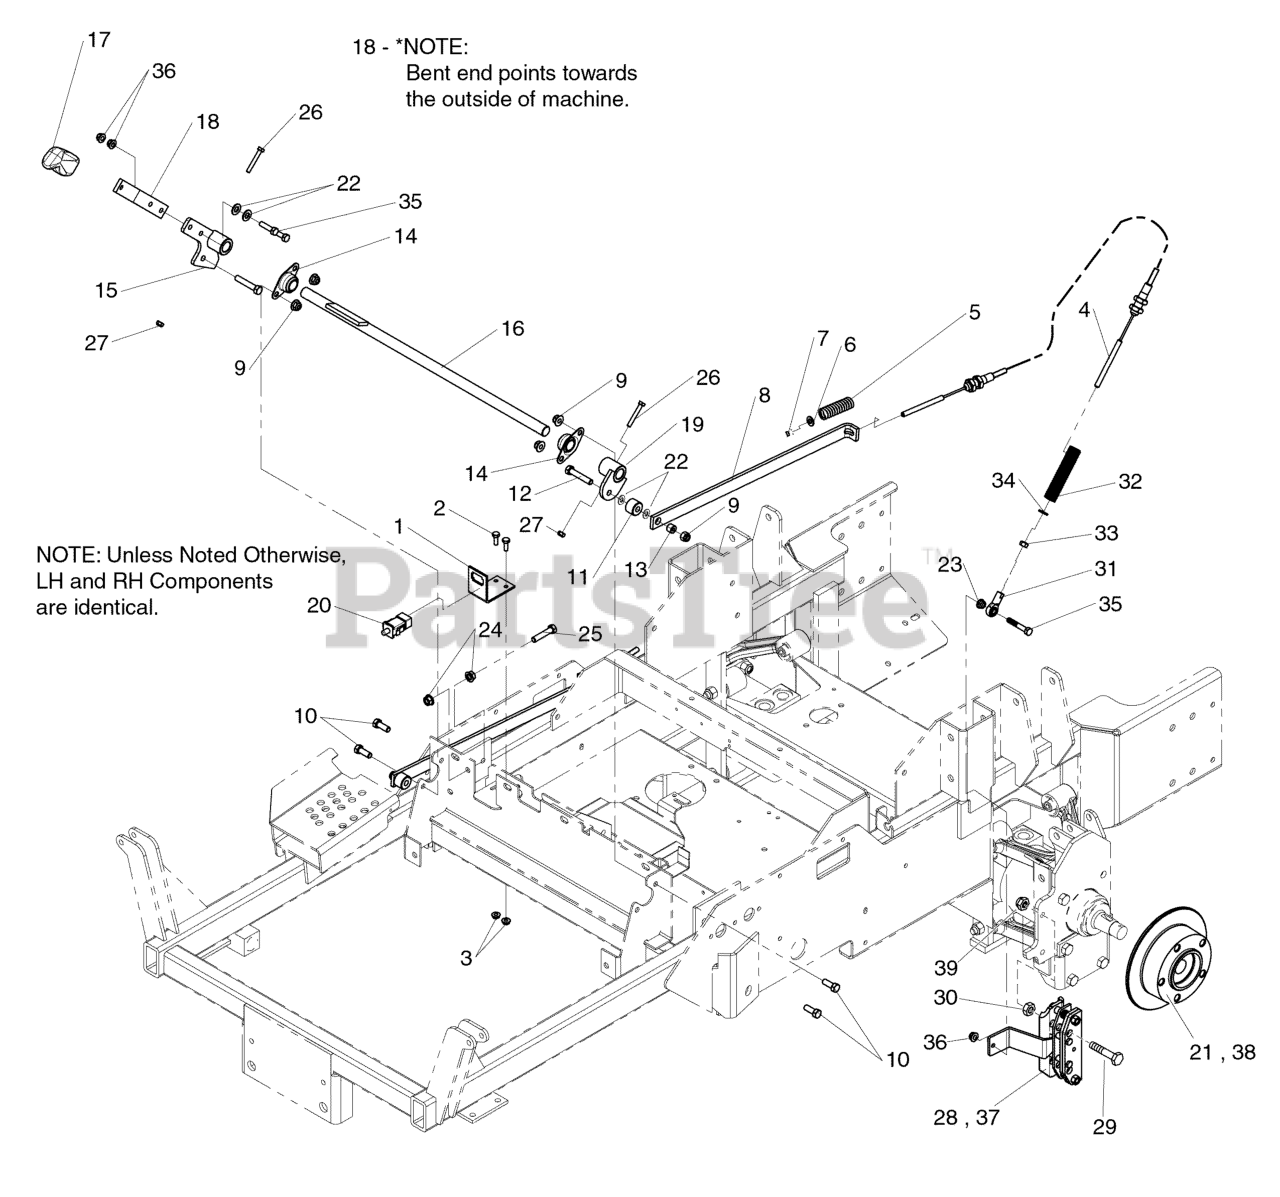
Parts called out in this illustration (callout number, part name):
1	BRACKET, SWITCH MOUNT - RED
2	BOLT, 1/4-20 X 3/4" GD5 YZ
3	NUT, 1/4-20 HEX SERR. FLANGE
4	CABLE, PARKING BRAKE
5	SPRING, BRAKE
6	WASHER, 5/16" SAE
7	NUT, 5/16-24 HEX NYLON LOCK
8	BRAKE, CABLE LINK - RED
9	NUT, 3/8-16 HEX NYLOCK FLANGE
10	BOLT, 3/8-16 X 3/4" GD5 CZ
11	SPACER, .39 X 1.00 X .75
12	BOLT, 3/8-16 X 2, GD5, CZ
13	SPACER, .38 X .50 X .27
14	BEARING, BRONZE FLANGE, 3/4
15	WELD, PIVOT HANDLE MOUNT - RED
16	WELD, SHAFT BRAKE LEVER - RED
17	GRIP, BLACK FLEXIBLE
18	HANDLE, BRAKE LEVER
19	PIVOT, LINKAGE MOUNT WELDMENT - BLK
20	SWITCH, DP NO/NC SNAP-IN
21	WHEEL HUB, COMPACT CALIPER (86720)
22	WASHER, 3/8 SAE
23	NUT, 5/16-18 HEX SERRATED FLANGE (SMALL)
24	NUT, 3/8-16 HEX SERRATED FLANGE
25	BOLT, 3/8-16 X 2" GD5 TFL CZ
26	BOLT, 1/4-20 X 1-1/2", GD5
27	NUT, 1/4-20 HEX SIDE LOCK
28	CALIPER, MECHANICAL
29	BOLT, 3/8-16 x 2-3/4, 1/2 SHOULDER
29	BOLT, 1/2-13 X 4" GD5 CZ
30	NUT, 1/2-13 HEX JAM
31	BALL JOINT 5/16-24 RH FEMALE BRONZE RACE
32	SPRING, COMPRESSION
33	NUT, 5/16-24 HEX
34	WASHER, 5/16" USS
35	BOLT, 5/16-18 X 1" GD5 YZ
36	NUT, 5/16-18 HEX NYLOCK FLANGE
37	COMPACT CALIPER, AUSCO (86978)
38	WHEEL HUB, COMPACT CALIPER (86720)
39	NUT, Hex, Side Lock, 3/8-16
39	NUT, 1/2-13 HEX NYLON LOCK
